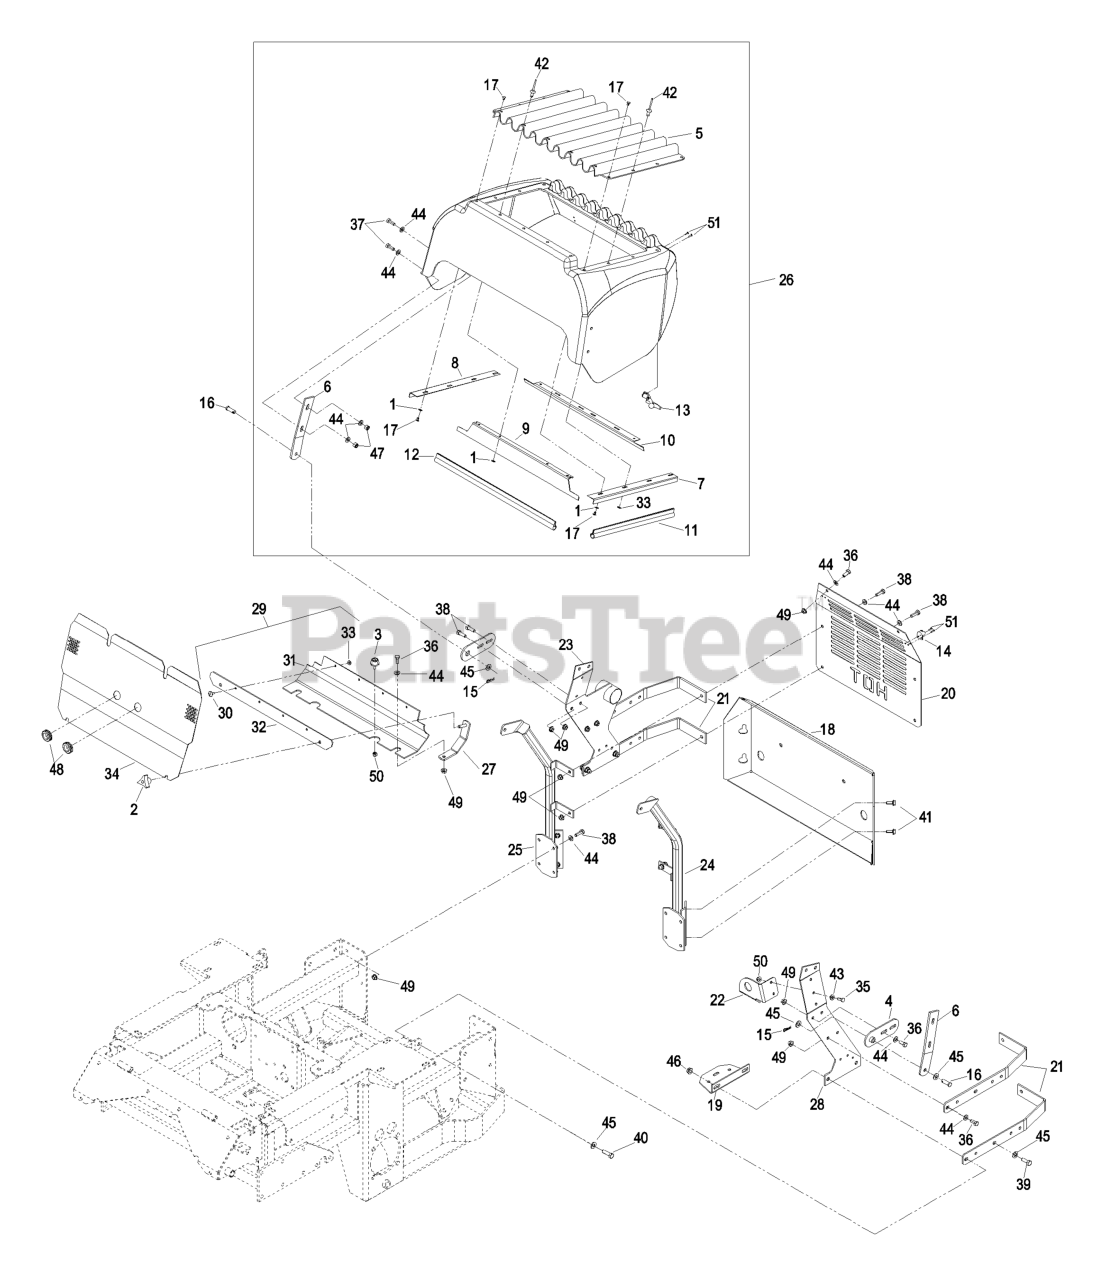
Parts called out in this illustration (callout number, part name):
1	WASHER-SPRING
2	KNOB-3 PRONG
4	SHACKLE-HINGE
5	SCREEN-RADIATOR
6	PLATE-HINGE, HOOD
7	ANGLE-RADIATOR, LH
8	ANGLE-RADIATOR, RH
9	ANGLE-RADIATOR, TOP
10	ANGLE-RADIATOR, BOTTOM
11	SEAL-TRIM
12	SEAL-TRIM
13	LATCH-RUBBER
15	PIN-COTTER
16	PIN-CLEVIS
18	WLD,REAR BUMPER
19	BRACKET-BOTTLE
20	GUARD-MUFFLER
22	BRACKET-BUZZER
23	RH RADIATOR AND AC SUPPOR
24	FRAME-UPPER, LH REAR
25	FRAME-UPPER, RH REAR
26	KIT,XP HOOD
27	MOUNT-BELT SHIELD, ENGINE
28	MOUNT-SIDE, LH
30	RIVET-POP
32	Strip, Belt Shield
33	WASHER-FLAT
35	SCREW-HH
36	SCREW-HH
37	SCREW-HH
38	SCREW-HH
39	SCREW-HH
40	SCREW-HH
41	SCREW-HHF
43	WASHER-FLAT
44	WASHER-PLAIN
45	WASHER-FLAT
46	NUT-HHF, WHIZ
47	NUT-LOCK, NI
48	GROMMET-RUBBER
